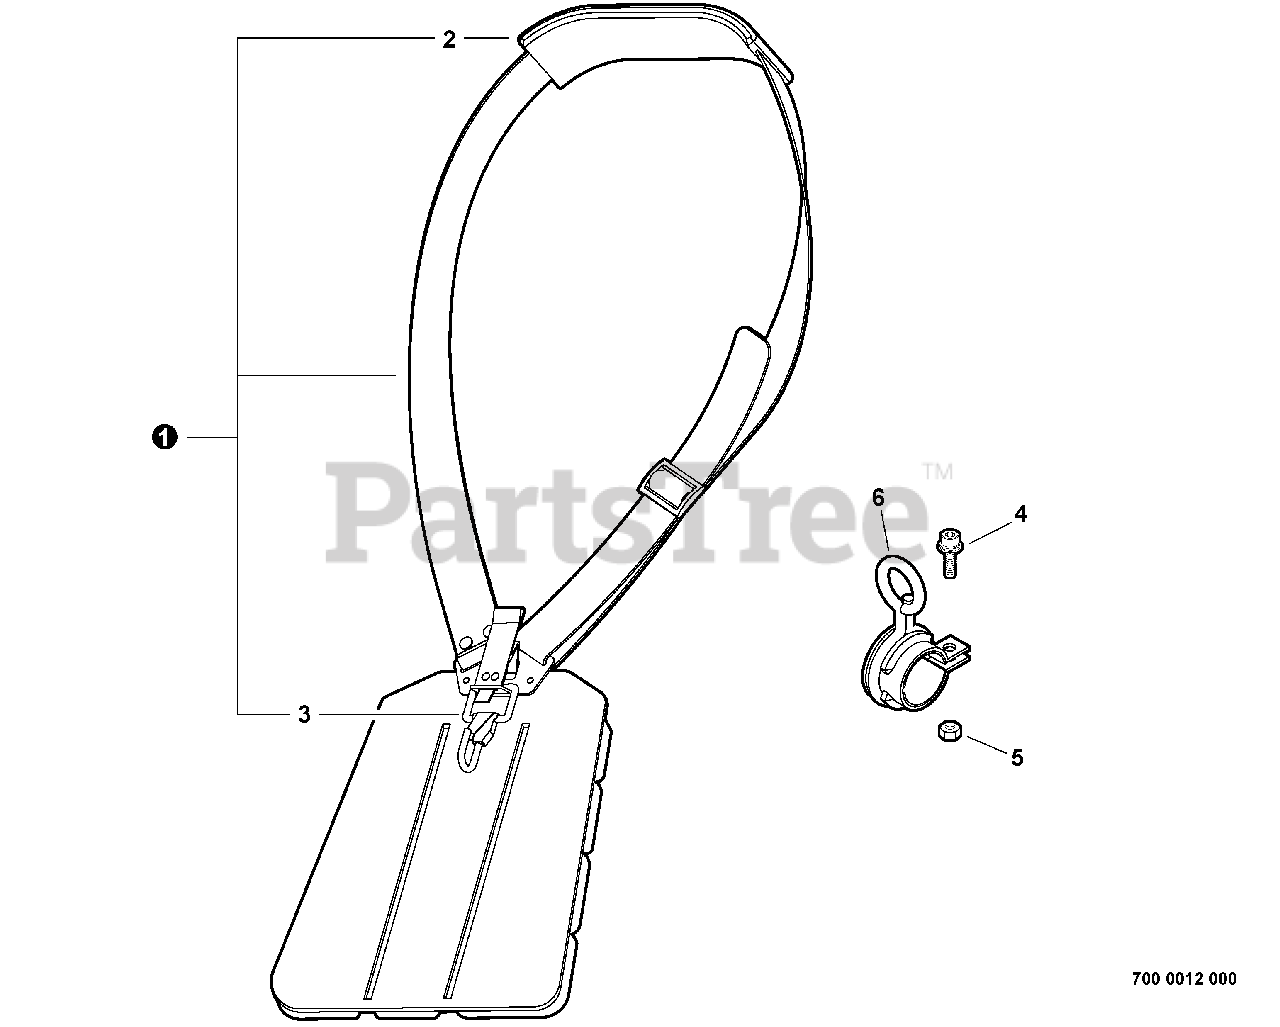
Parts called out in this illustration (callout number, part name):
1	HARNESS ASSY
2	PAD, SHOULDER
4	SCREW - 5X12
6	HANGER ASSY
